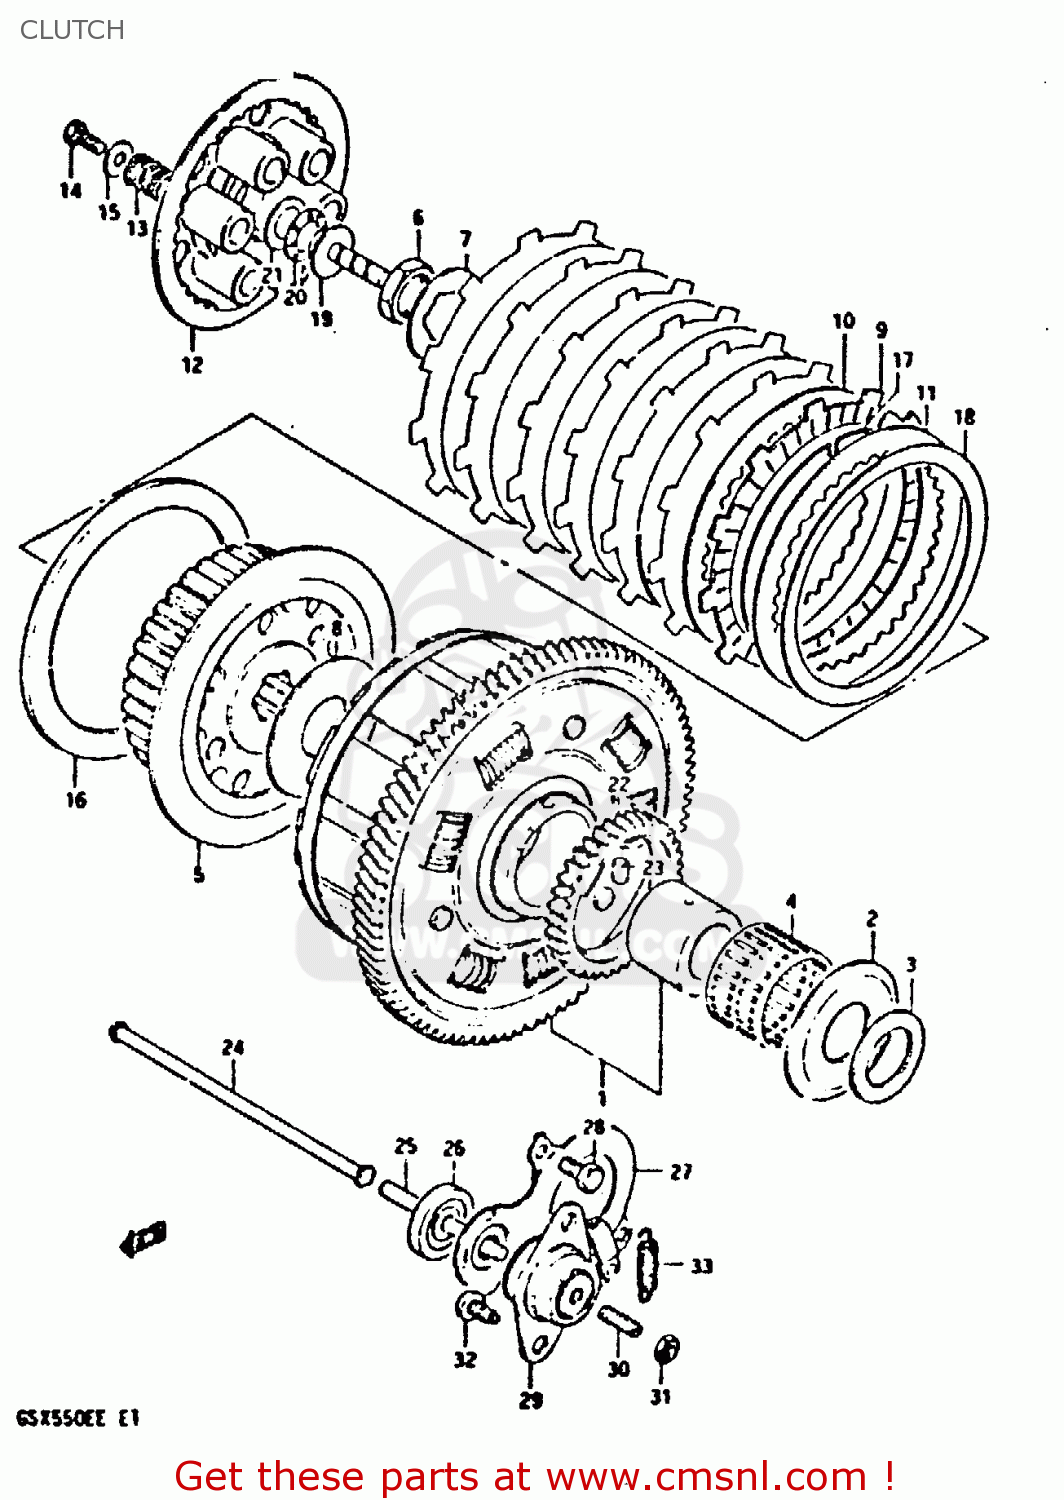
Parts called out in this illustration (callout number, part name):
1	GEAR ASSEMBLY,PRIMARY DRIVE
2	WASHER
3	WASHER
4	BEARING(40X45X32)
5	HUB,CLUTCH SLEEVE
6	NUT
7	WASHER,LOCK
8	WASHER
9	PLATE,CLUTCH DRIVE (NAS)
10	PLATE,CLUTCH DRIVEN (NAS)
11	PLATE,CLUTCH DRIVEN(T:2.0) (NAS)
12	DISC,CLUTCH PRESSURE
13	SPRING
14	BOLT, UPPER
15	WASHER
16	SEAT,WAVE WASHER
17	RING,STOPPER
18	WASHER
19	PIECE,CLUTCH PUSH
20	BEARING(15X28X2)
21	WASHER
22	GEAR,OIL PUMP DRIVE
23	PIN
24	ROD,CLUTCH PUSH
25	ROD,CLUTCH PUSH,L
26	OIL SEAL
27	PLATE,CLUTCH PUSH ROD
28	BOLT
29	SCREW ASSY,CLUTCH RELEASE
30	SCREW(6X25)
31	NUT 6MM
32	SCREW
33	SPRING
